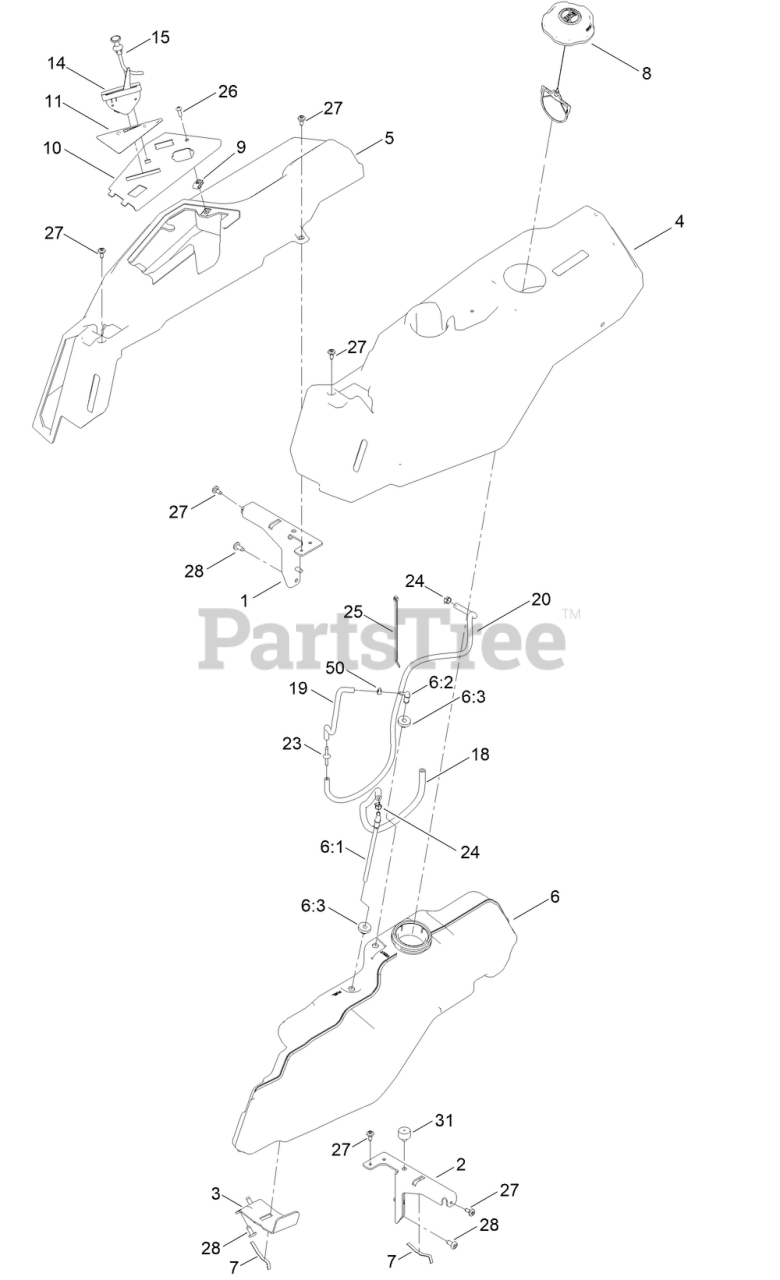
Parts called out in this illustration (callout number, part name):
1	SUPPORT-POD, RH
2	SUPPORT-POD, LH
3	SUPPORT-TANK, FUEL
4	POD-LH
5	POD-RH
6	TANK-FUEL ASM
6:1	CONNECTOR-ELBOW, 90 DEG
6:2	FITTING-ELBOW 90
6:3	BUSHING
7	SPRING
8	CAP-FUEL, RATCHETING
10	PANEL - CONTROL
11	DECAL-PANEL, CONTROL
14	CABLE-THROTTLE
15	CABLE-CHOKE
18	HOSE-FUEL
19	HOSE-FUEL
23	ADAPTER ORIFICE
24	CLAMP-HOSE
25	TIE-CABLE
26	SCREW-PRH
27	SCREW-SHOULDER
31	BUMPER-GROMMET
50	CLAMP-HOSE
